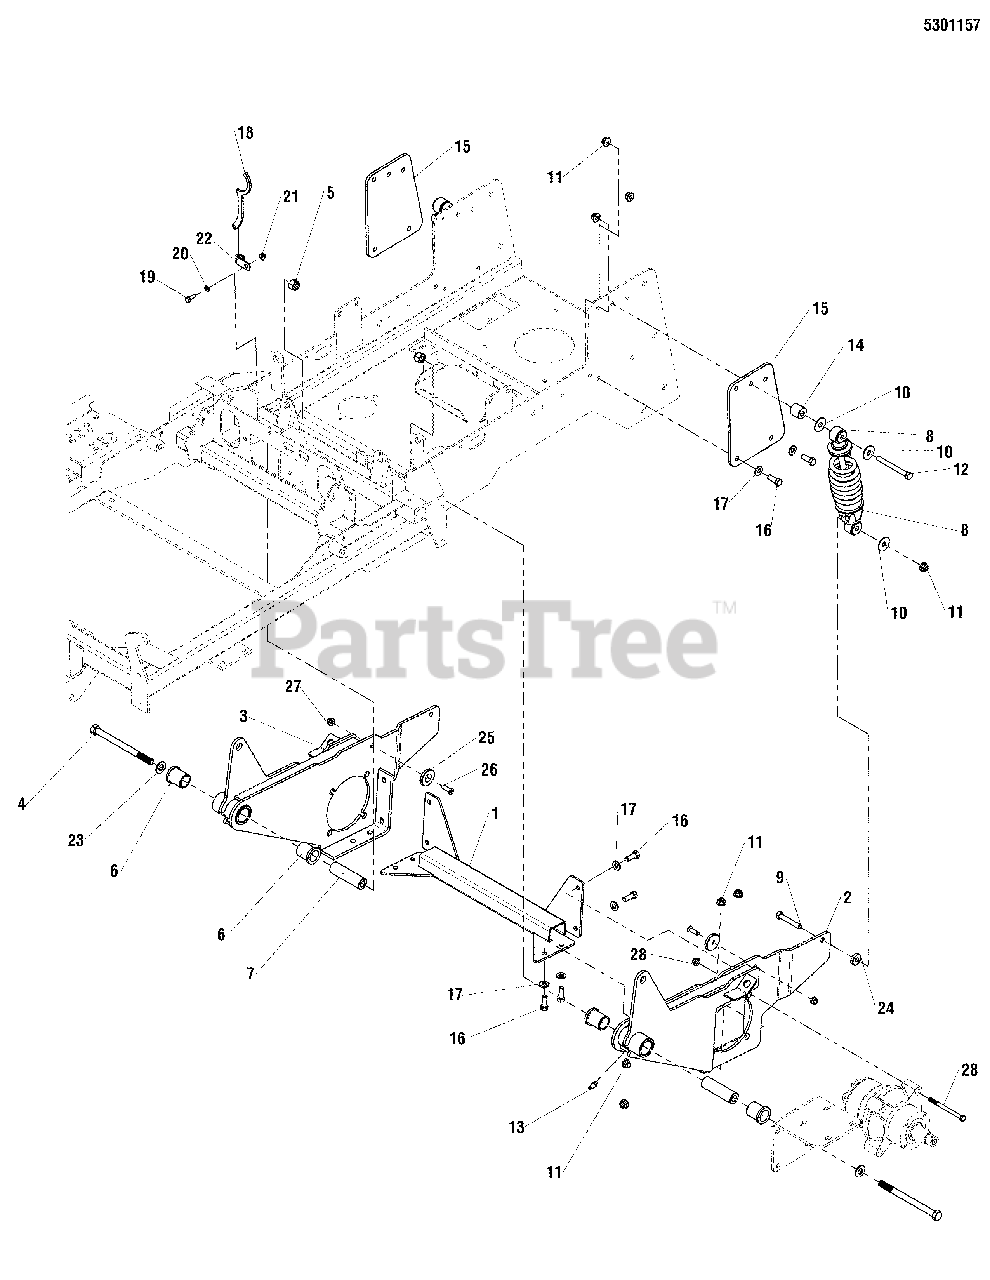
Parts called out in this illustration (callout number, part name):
1	KIT, TIE BAR (5404064A)
2	WELD, MOTOR MOUNT - LH-IS500-ORG
3	WELD, MOTOR MOUNT - RH-IS500-ORG
4	BOLT, 1/2-13 X 6-1/2 GD5 YZ
5	NUT, 1/2-13 HEX NYLON LOCK
6	BUSHING, FLANGE
7	SPACER, .52 X 1.00 X 3.42
8	SHOCK ABSORBER, # 7417-106
9	BOLT, 3/8-16 X 2 GD5 YZ
10	WASHER, 3/8 FENDER
11	NUT, 3/8-16 HEX NYLOCK FLANGE
12	BOLT, 3/8-16 X 3-1/2 GD5 YZ
13	GREASE FITTING, 45 DEGREE
14	SPACER, .390 X 1.00 X 1.00 - YZ
15	PLATE, FRAME SUPPORT - IS500-ORG
16	BOLT, 3/8-16 X 1-1/4" GD5 YZ
17	WASHER, 3/8 GD.9 FLAT
18	SPANNER WRENCH
19	BOLT, 1/4-20 X 3/4 GD5 YZ
20	WASHER, 1/4 SAE (5025154)
21	NUT, 1/4-20 HEX NYLOCK FLANGE (5025391)
22	CLAMP, 5/16, DOUBLE, WIRE & TUBE
23	WASHER, 1/2 SAE
24	SPACER, .39 X 1.00 X .25
25	SPACER, .34 X 1.54 X .25 UHMW
26	SCREW, 5/16-18 X 1, PHILLIPS HD, BZ
27	NUT, 5/16-18 HEX NYLOCK FLANGE
